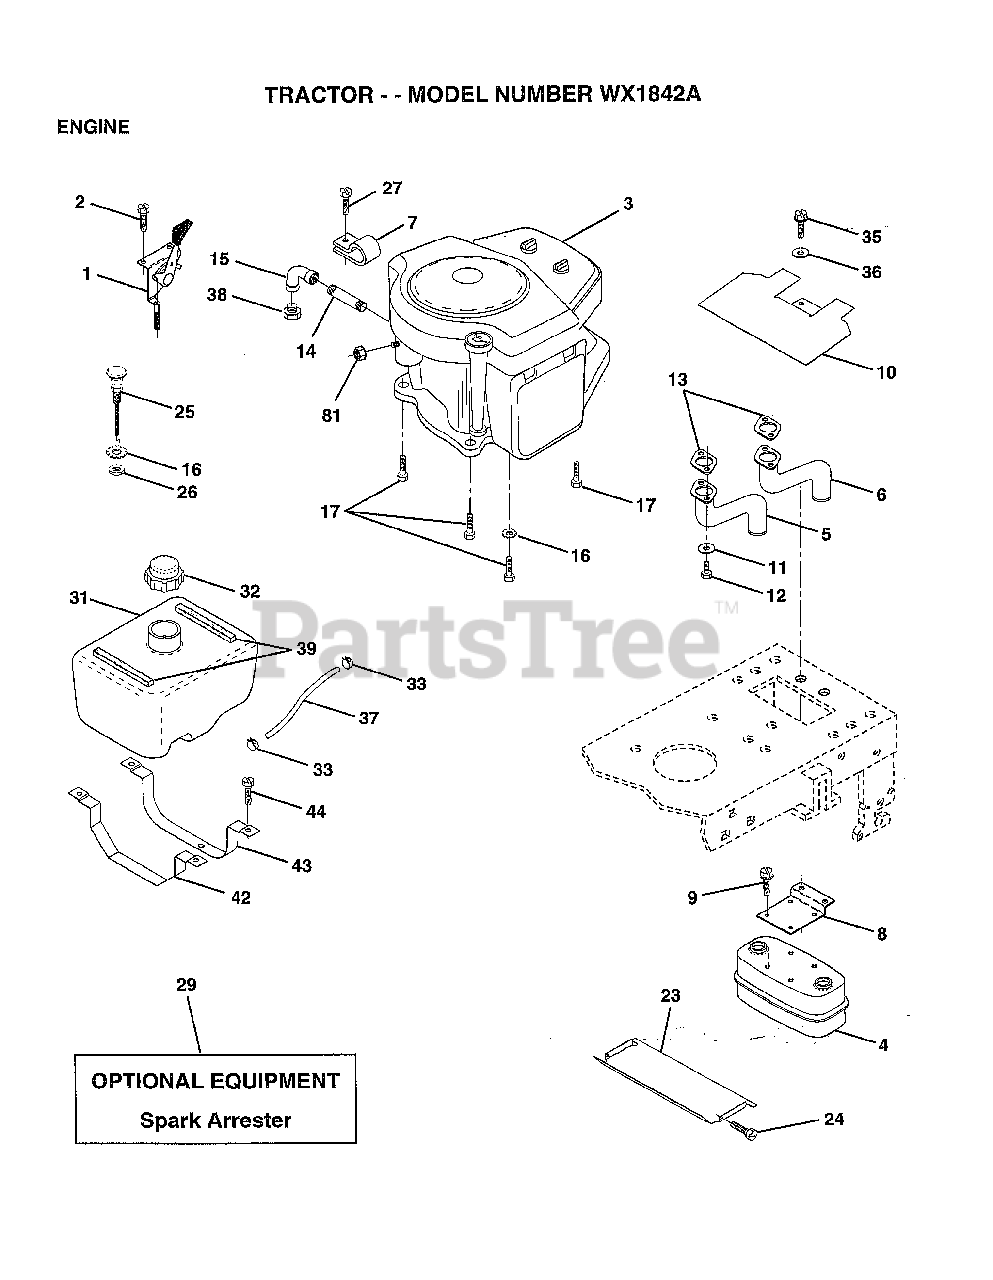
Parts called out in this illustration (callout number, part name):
2	SCREW LT
5	EXHAUST.B&S.18.LH
6	EXHAUST.B&S.18.RH
7	CLAMP.TUBE.DBL.EN
8	BRACKET MUFFLER
9	SCREW ST
10	SHIELD.HEAT.
11	LOCKWASHER
13	GASKET MUFFLER
14	PIPE NIPPLE LT
15	ELBOW
16	LOCKWASHER
17	SCREW LT
23	HEAT SHIELD
24	SCREW
25	CONTROL.CHOKE.37
27	SCREW.10-24X1/2
31	TANK FUEL 1.9 NAT
32	CAP ASM FUEL
33	HOSE CLAMP
35	SCREW
36	WASHER
37	FUEL LINE T
39	"STRIP,FORM"
42	"STRAP,TANK"
43	"STRAP,TANK "
44	SCREW
81	NUT
